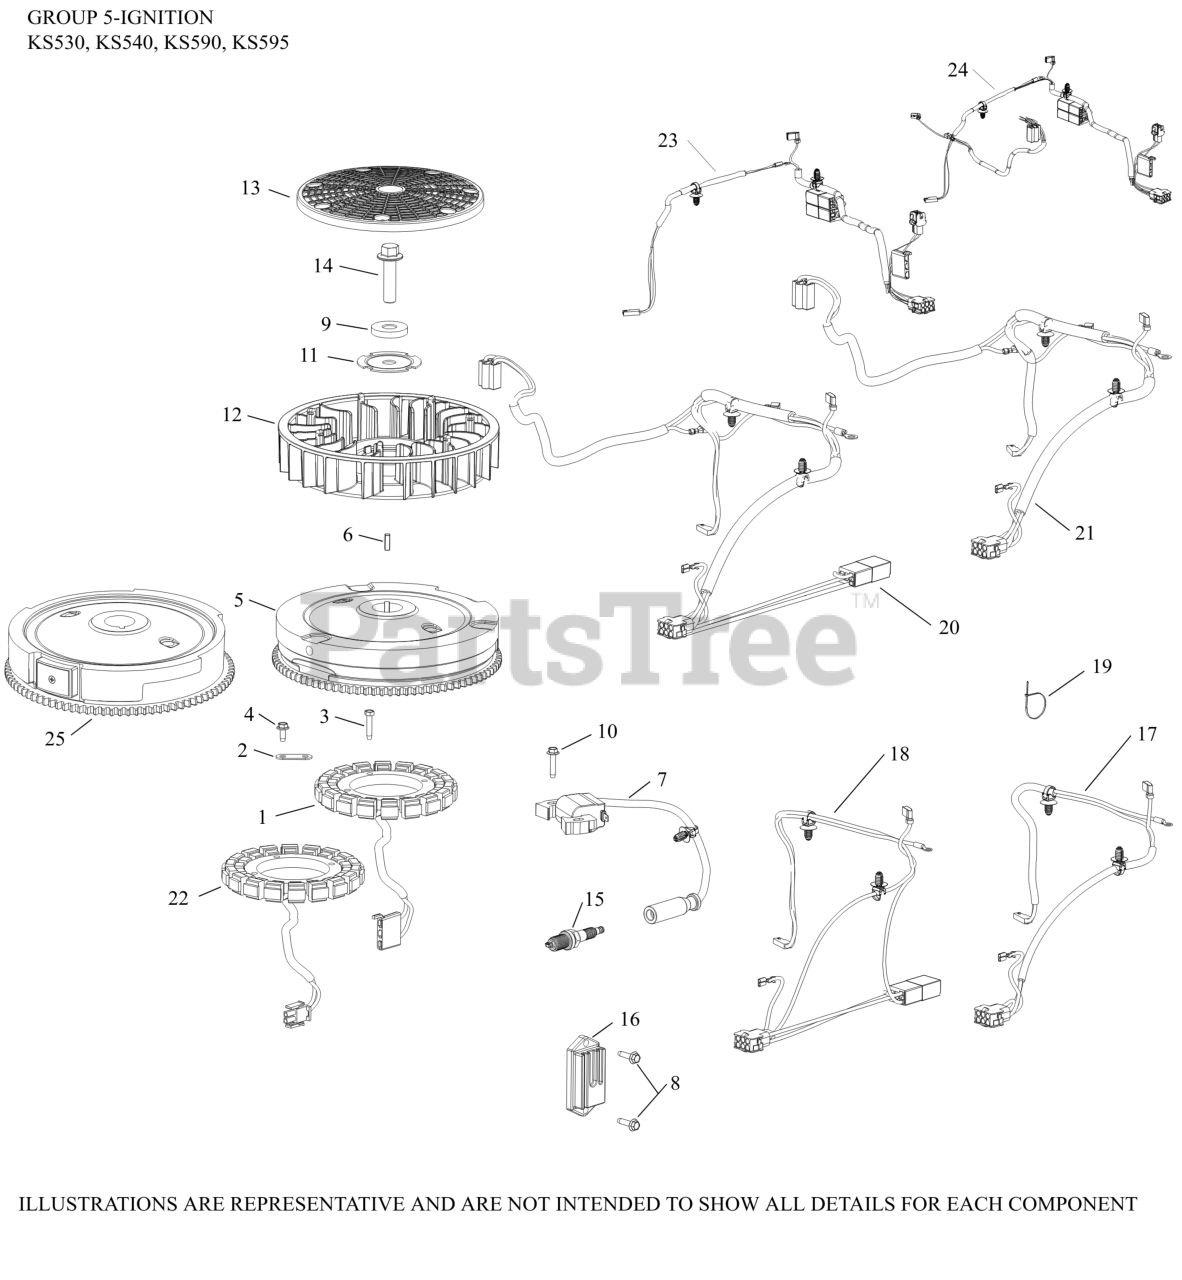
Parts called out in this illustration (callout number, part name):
2	CLIP, STATOR WIRE
3	SCREW, THREAD FORMING
4	SCREW, FLG THD FRM M5X0.8X13
5	FLYWHEEL, ASSY
6	KEY, SQUARE
7	MODULE, INDUCTIVE IGNITION COIL
8	SCREW, THD FRM-USE 25 086 473-S
9	WASHER, FLAT
10	SCREW, THREAD FORMING
11	PLATE, FAN MOUNTING
13	SCREEN, GRASS
14	SCREW, HEX FLANGE
15	PLUG, SPARK
16	REGULATOR/RECTIFIER 12/15A HALF-WAVE STD
22	STATOR ASSEMBLY, 15 AMP
23	HARNESS, WIRING W/COMBO FSO & SB
